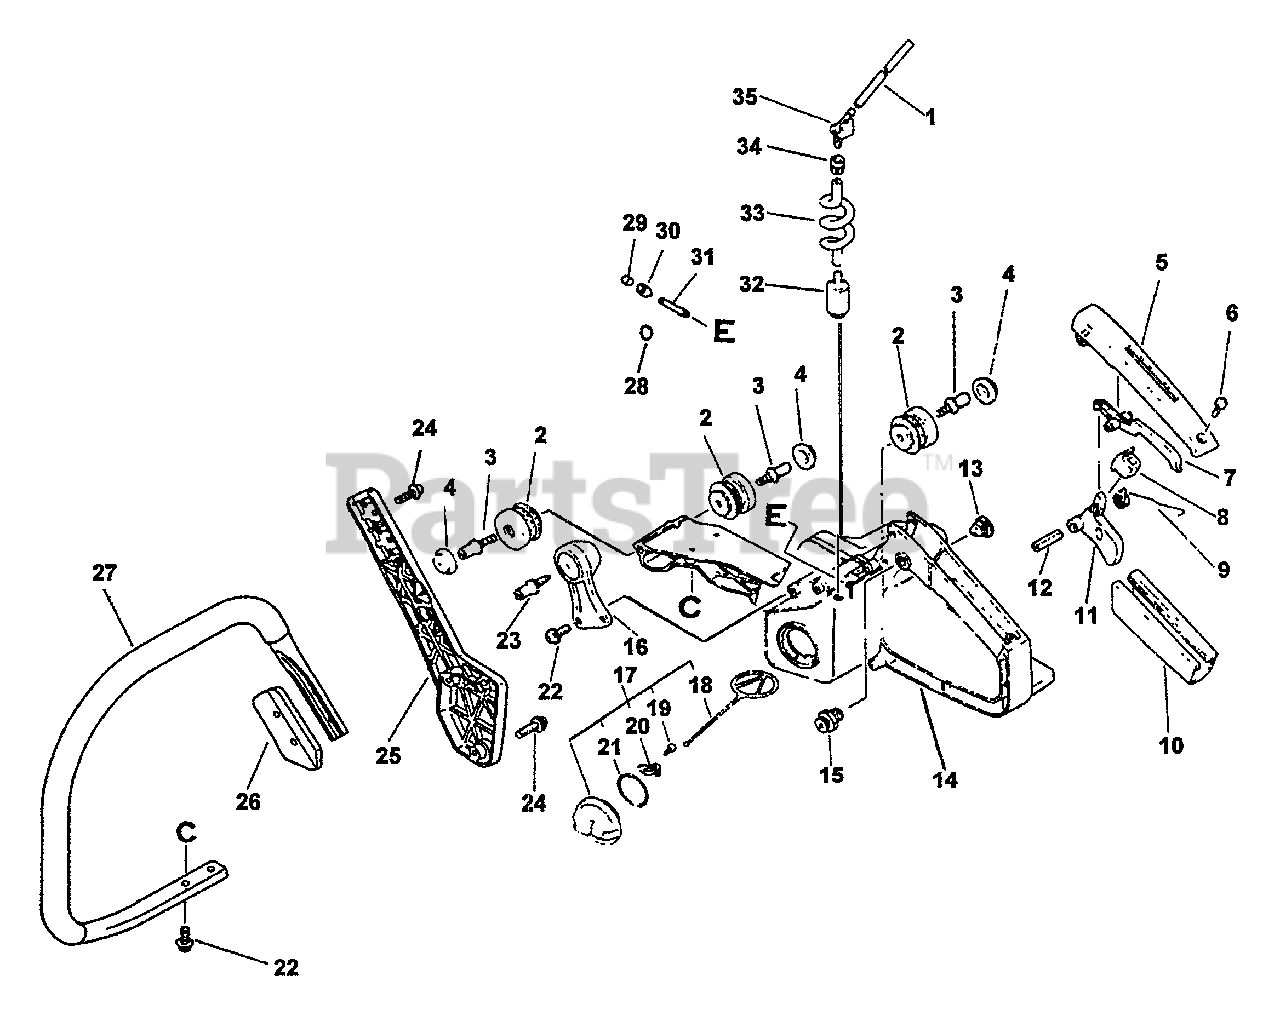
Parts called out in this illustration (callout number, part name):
1	PIPE - 3X6X100 -- BLACK
4	CAP, CUSHION
5	COVER, HANDLE
6	SCREW - 4X14
7	LEVER, TRIGGER LOCKOUT
9	SPRING, TRIGGER
10	GRIP, HANDLE
11	TRIGGER, THROTTLE
12	PIN - SPRING -- 5X25
14	HANDLE - REAR
15	LATCH, THROTTLE
17	CAP ASSY
18	CONNECTOR, CAP
19	SCREW - 3X8
20	RETAINER
21	O-RING - 29
22	SCREW - 5X14
24	SCREW - 5X20
25	BRACKET, HANDLE
26	BRACKET, HANDLE
27	HANDLE - FRONT
28	CLIP - 5.5
29	VENT, FUEL TANK
30	COVER, VENT
31	PIPE - VENT
32	FILTER, FUEL
33	PIPE - BLACK
34	GROMMET
35	CONNECTOR, PIPE
